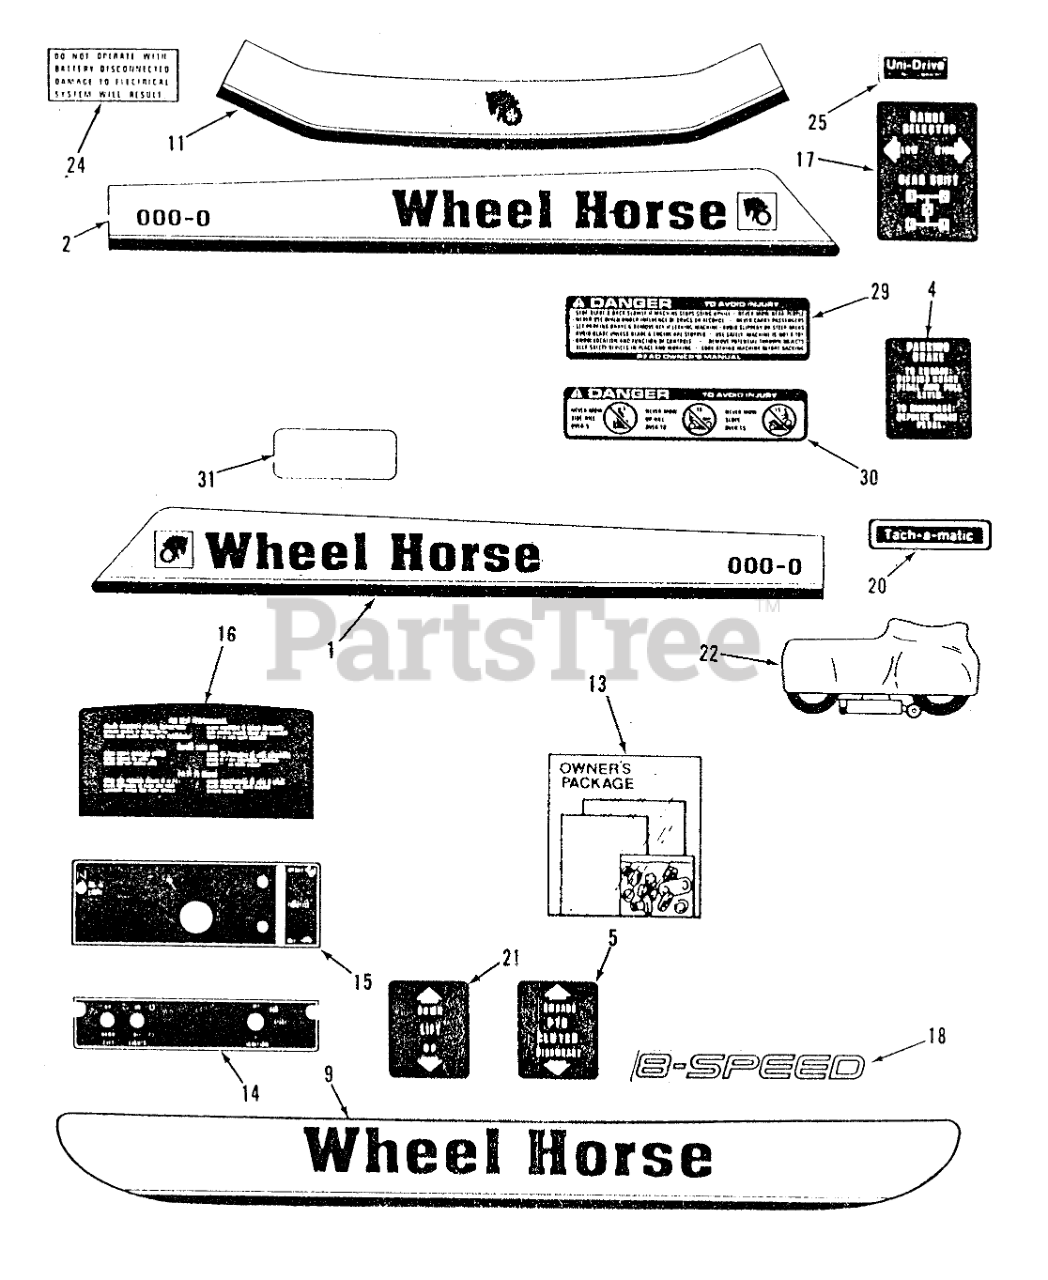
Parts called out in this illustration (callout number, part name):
1	HOOD DECAL RH
2	HOOD DECAL LH
4	DECAL-PARKING, BRAKE
5	DECAL PTO
9	Decal-Rear Fender
11	Decal-Hood Front
13	Loose Parts Package
14	DECAL BACK PLATE
15	DECAL LOWER DASH
16	Decal-Rear Hood
18	DECAL 8SPD
20	DECAL-TACHAMATIC
21	DECAL-LIFT
22	Vinyl Tractor Cover
24	DECAL ELECT SYSTEM
25	Decal-Unidrive
29	Decal-Danger
30	Decal-Danger
31	DECAL-OVERLAY
